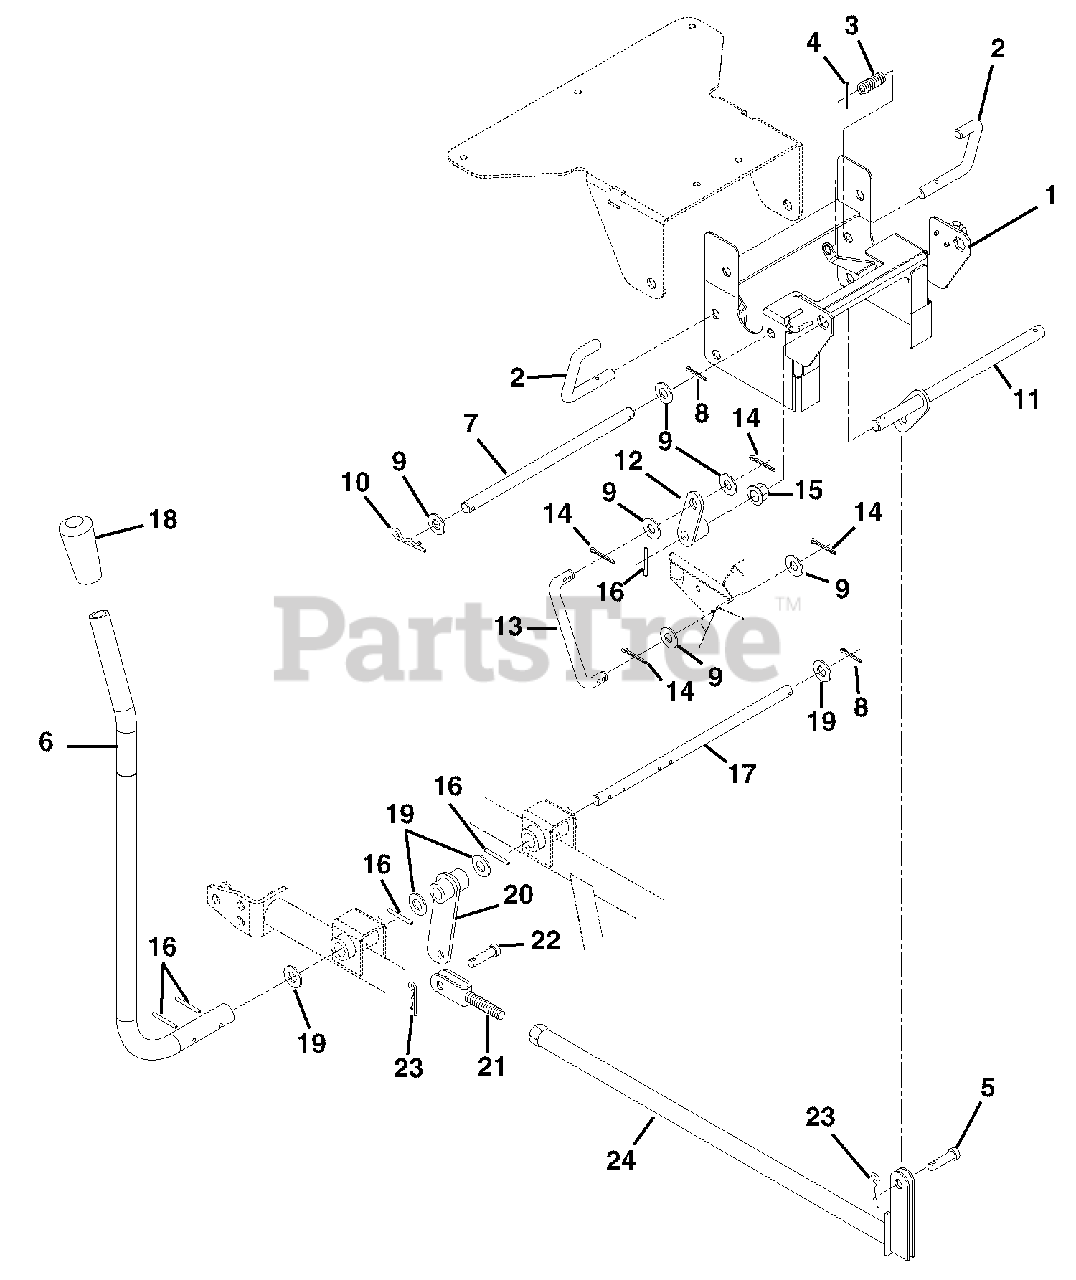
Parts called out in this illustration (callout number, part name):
1	BLADE PIVOT
2	PIN, LATCH
3	SG-COMP .072X.77X1.75
4	PIN-ROLL .188X1.00
5	CLEVIS PIN - .500 DIA. X 1.000
6	LIFT LEVER
7	ROD, PIVOT
8	@PIN-CTR .12X1.25 EXTPRSQCT YZ
9	@WSHR-FL-STL.656X1.31X.095 YWZ
10	PIN-HAIR-INT .17X.68X3.50 YWZC
11	PIVOT ROD
12	ARM, LIFT
13	LINK, LIFT
14	@PIN-CTR .12X1.00 EXTPRSQCT YZ
15	BSHG-FLG .750X.873HEXX.53X1.18
16	PIN-GRV .250X1.50 TP A
17	LIFT SHAFT
18	GRIP,HANDLE BAR
19	WSHR-FL-STL.754X1.125X.062YWZC
20	LEVER, ACTUATOR
21	CLEVIS R.H.
22	PIN-CLEV .494X1.25 YWZC
23	PIN-HAIR-INT .15X2.937 YWZC
24	LIFT TUBE
